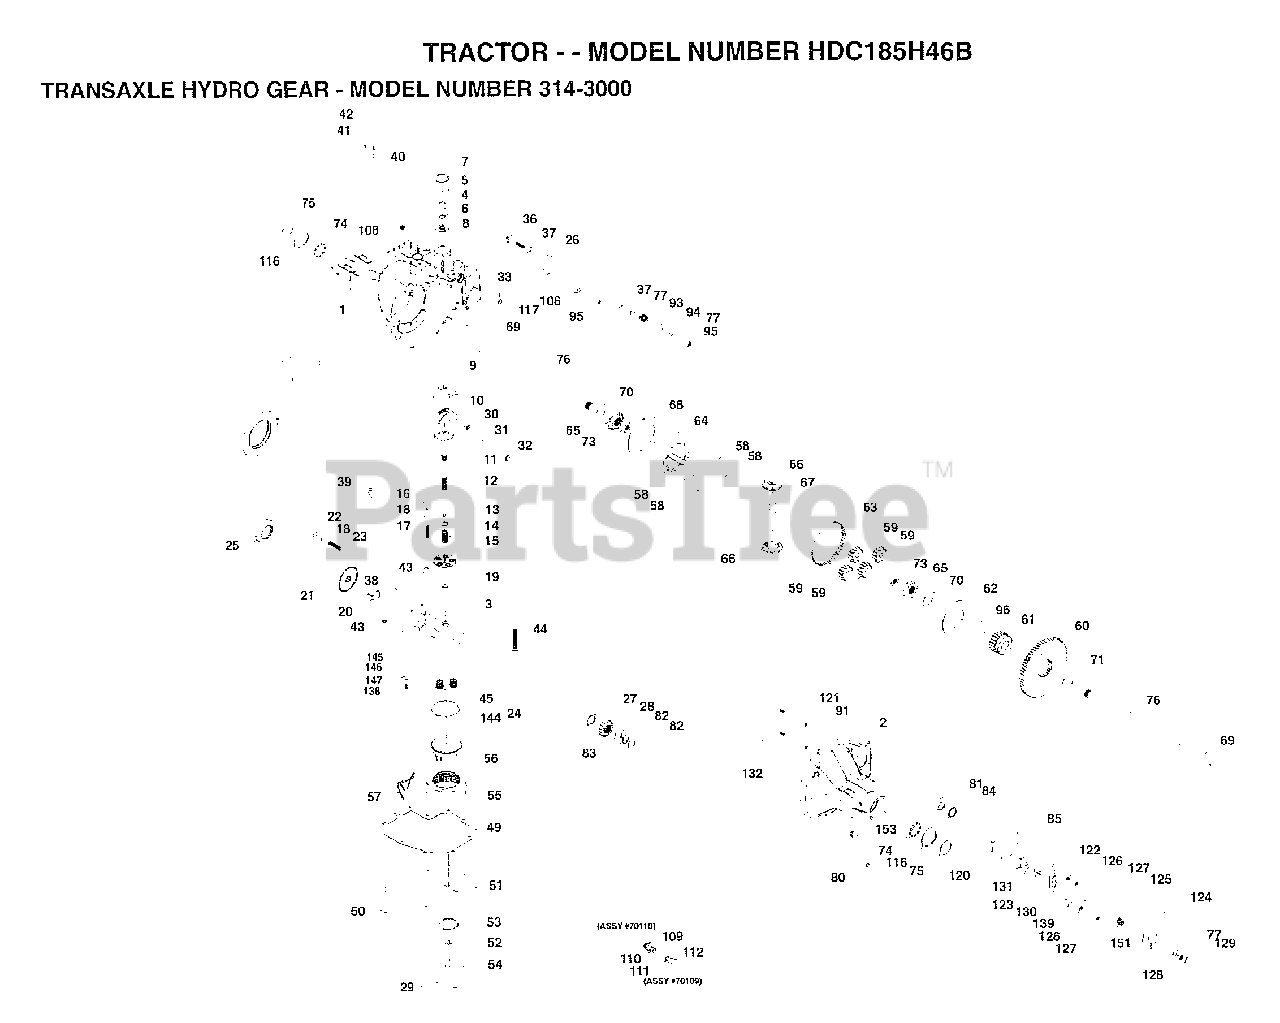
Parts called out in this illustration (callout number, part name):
1	MAIN HOUSING ASSY
2	RH HOUSING ASSY
3	CENTER SECTION ASSY
4	SPACER
5	SEAL.9008000-0128
6	RING.RET.2003016.
7	RING.RET.2003052.
8	BEARING.(50552)42X68X16
9	CRADLE- 2003023.
10	SWASHPLT.2003087.
11	BEARING.THU.50551
12	INPUT SHAFT
13	WASHER.2003017
14	SPRING.2003014.
15	BLOCK.CLYN.70079.
21	BLOCK.CYLIN.70082
24	OUTPUT (MOTOR) SHAFT
25	BEARING.THU.50552
26	CONTROL ARM
27	SPACER
28	16T PINION GEAR
29	CAPSCREW, M6 X 1-22
30	GUIDE.2000015.
31	TRUNNION ARM
32	TRUNNION BUSHING
33	SEAL.9008000-0126
36	5/16-24 STUD
37	PUCK.DAMPER.50281
39	ACTUATOR.2003555
40	SEAL.LIP.45074
41	ARM.BYPASS.50270
42	RING.RETAIN.44870
43	PIN.HYDRO.50002
44	BOLT.3/8-24.50016
49	GASKET, LOWER
50	SCREW
51	LOWER COVER
52	GEROTOR ASSY
53	0RING.90041011340
54	GEROTOR COVER
55	FILTER
56	CHARGE MANIFOLD
57	RETAINER, MOTOR BEARING
58	PIN, CARRIER
59	15T PLANET GEAR
60	67T SPUR GEAR
61	21T SUN GEAR
62	PLANET THRUST PLATE
63	51T RING GEAR
64	PLANETARY CARRIER
65	MITER GEAR, DIFF. (SPLINED)
66	MITER GEAR, DIFF.
67	SHAFT, DIFFERENTIAL
68	DIFF. THRUST PLATE
71	WASHER
73	HEX JAM NUT, 5/8-18
75	SEAL
76	SHAFT, AXLE
77	WASHER HYD 44130
79	GASKET.44813
80	SCREW
81	NEEDLE BEARING
82	WASHER
83	RETAINING RING
84	LIP SEAL
85	BRAKE DISK
93	SPRING.HYD.50277
94	SPACER.HYD.50278
95	NUT.LOCK.HX.50108
96	SLEEVE BEARING
106	SPACER, TRUNNION
109	O-RING.ASM.70110
111	CAP.VENT.70109
116	RETAINING RING
117	STD HDLS PIN
120	PUCK BRAKE 44132
124	ARM, BRAKE
125	PIN BRAKE 44127
126	LOCKWASHER, 1/4
127	NUT, 1/4-20
130	SPACER
131	PUCK PLATE 44134
138	SCREW
145	CHARGE RELIEF SPRING
147	PLATE, RELIEF
151	COMP. SPRING, BRAKE ANTI-DRAG
153	PLUG.9005110-5600
